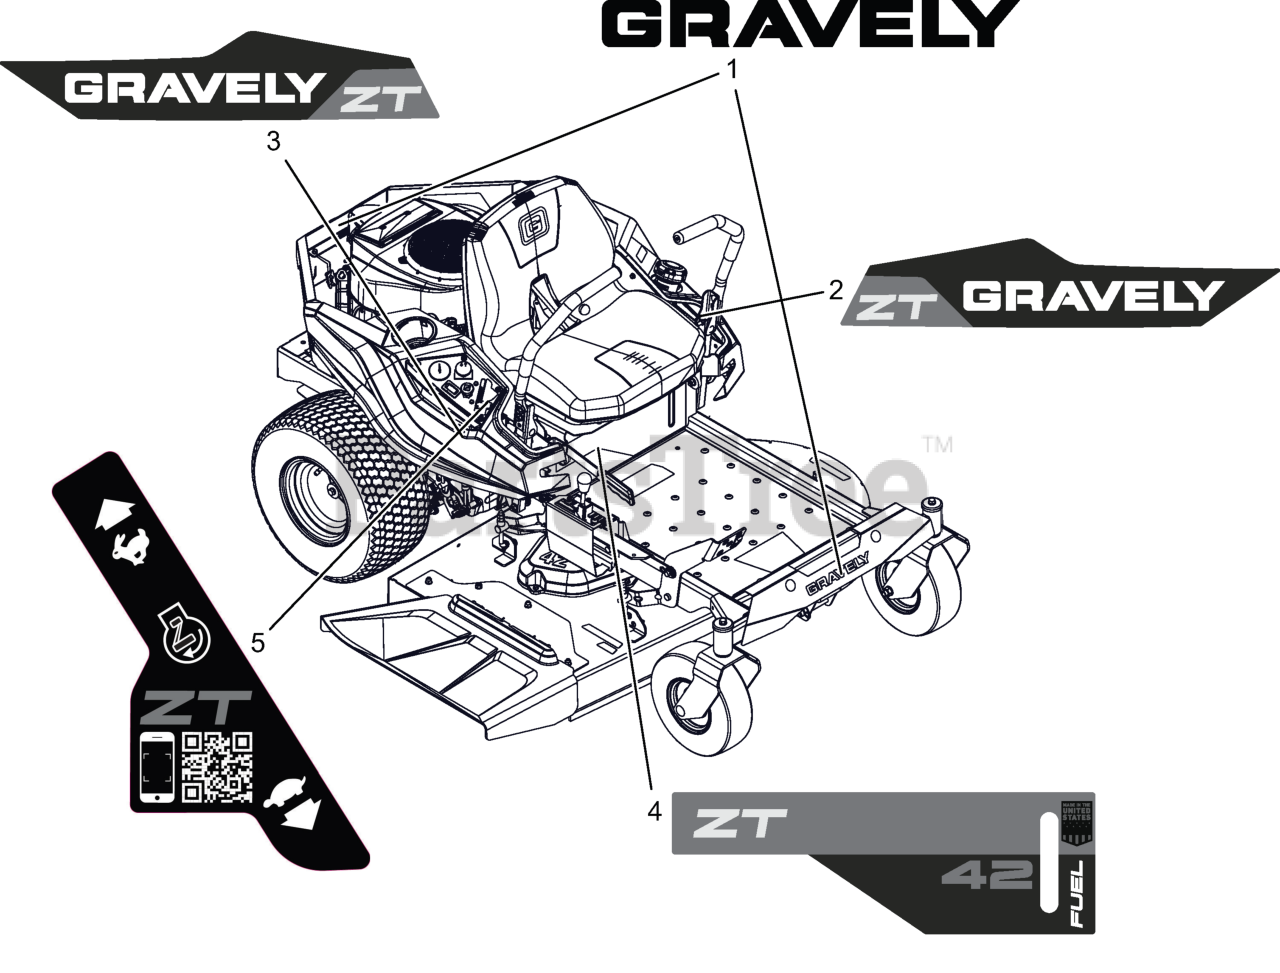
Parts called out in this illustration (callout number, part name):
1	DECAL- GRAVELY
2	DECAL, GRAVELY (FENDER LH)
3	DECAL, GRAVELY (FENDER RH)
4	DECA;. ZT42 KICKPLATE
5	DECAL, THROTTLE CONTORL -ZT
